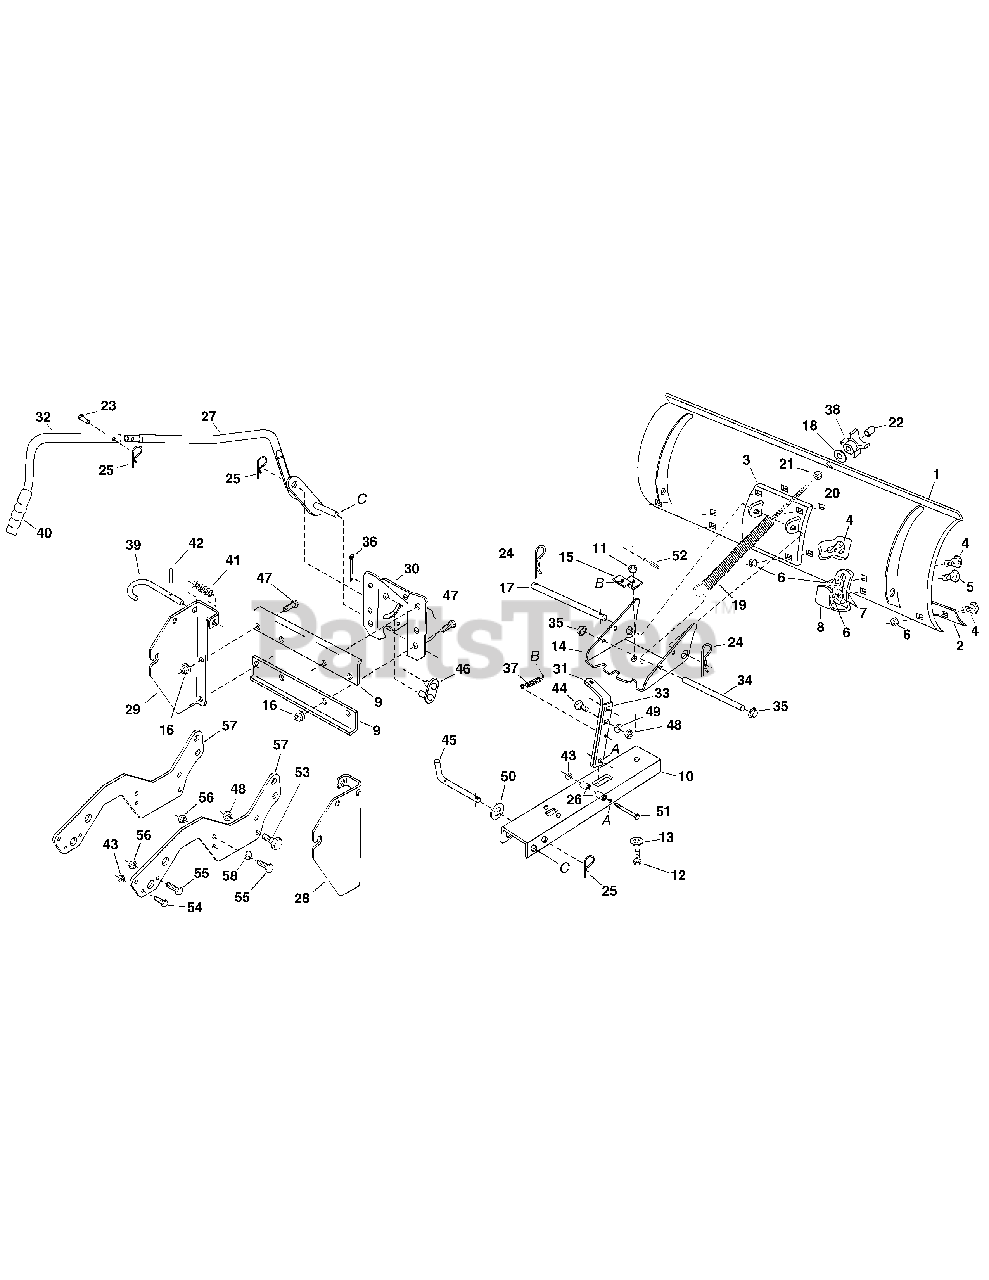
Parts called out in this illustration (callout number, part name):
1	Blade - 46"
2	Wear Plate - 46"
3	Reinforcement Plate Assembly
4	Bolt, Carriage 5/16-18 x 3/4
6	Hex Lock Nut 5/16-18 Thread
7	Washer, 5/16"
8	Skid Shoe
9	Bracket, Angle Support
10	Push Channel
11	Hex Lock Nut 6, 1/2 13 Thread
12	Bolt, Special Pivot
14	Plate, Pivot 7 Ga
15	Bracket, Spring Mt.
16	Flanged Lock Nut, 3/8-16 Thread
17	Shaft, Pivot
18	Washer, 3/8" STD
19	Spring, Blade Adjust
20	Hex Bolt, 3/8-16 x 3 -1/2"
21	Hex Nut, 3/8-16 Thread
22	Plastic Cap
23	Pin, Clevis 1/4" x 1-1/2"
24	Pin Hair Cotter No. 4 (1/8")
25	Pin Hair Cotter No. 3 (3/32")
26	Spacer, .28 ID x 1"
27	Lift Handle Assembly, Lower
28	Hitch Bracket, RH
29	Hitch Bracket, LH
31	Angle Lock Bar (Long)
32	Lift Handle Upper
33	Angle Lock Bar (Short)
34	Spring Mount Rod
35	Palnut 3/8
36	Cotter Pin 1/8" x 1
37	Angle Lock Spring
39	Pin, Attachment
40	Handle, Grip
41	Spring, Compression
42	Pin, Spring 3/16" x 1
43	Hex Lock Nut 1/4-20 Thread
45	Channel Pivot Pin
46	Lift Link Assembly
47	Hex Bolt, 3/8-16 x 3 -1"
48	Hex Lock Nut, 3/8"-16 Thread
49	Lock Washer 3/8"
51	Hex Bolt, 1/4-20 x 3 1/4" LG. GR 5
52	1/4" x 1" Spring Pin
53	Shoulder Bolt 3/8-16 x 1/2"
56	Hex Nut, 5/16-18 Nylock
57	Frame Bracket
